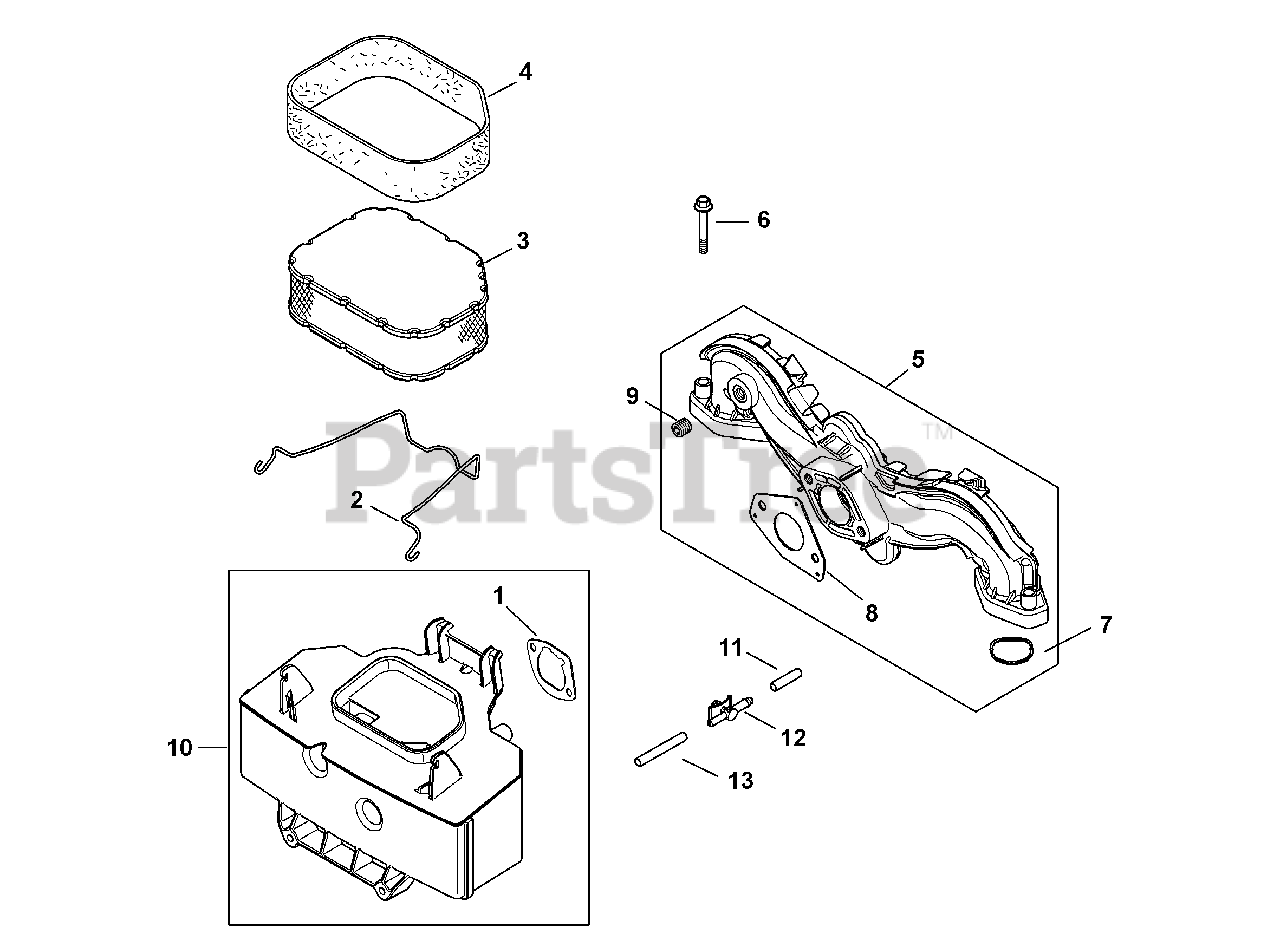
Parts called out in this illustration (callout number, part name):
1	Air Cleaner Base Gasket
2	Air Cleaner Element Latch
3	Air Filter & Pre-Cleaner Elements
4	Pre-Cleaner Element
5	Intake Manifold Kit
6	Flg. Screw, M6 x 1.0 x 40
7	O-Ring, Intake Port
8	Carburetor Gasket
9	Pipe Plug, 1/8"
10	Air Cleaner Base
12	Evaporative Connector
13	Evaporative Hose, 20"
